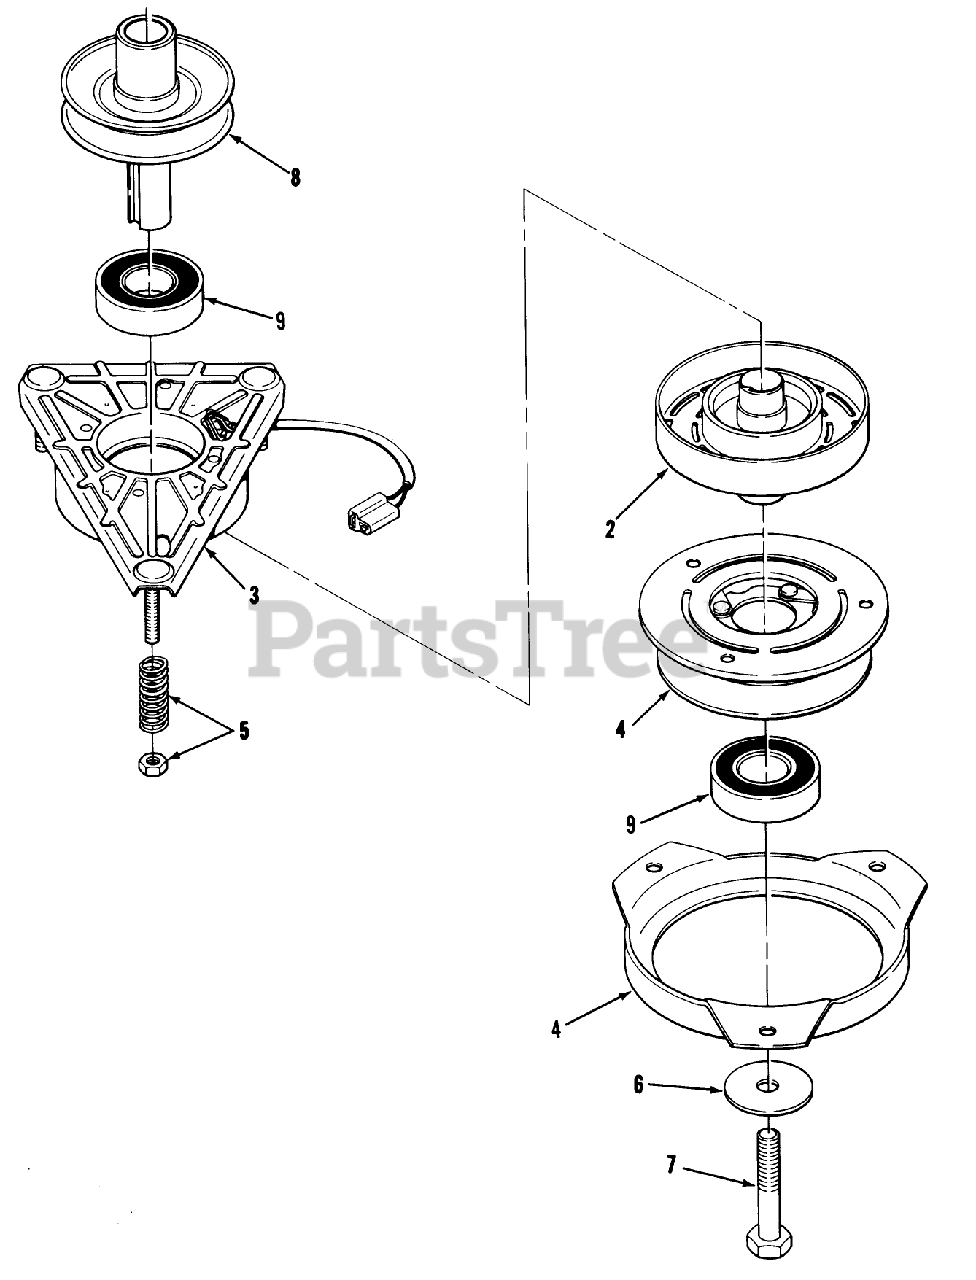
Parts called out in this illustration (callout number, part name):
1	Electric Clutch Assy (includes items 2, 3, 4 5)
4	ASS'Y-ARMATURE
5	ACCESS SPRING & NUT
6	WASHER
8	PULLEY-ENGINE
9	BEARING-ELEC CLUTCH
